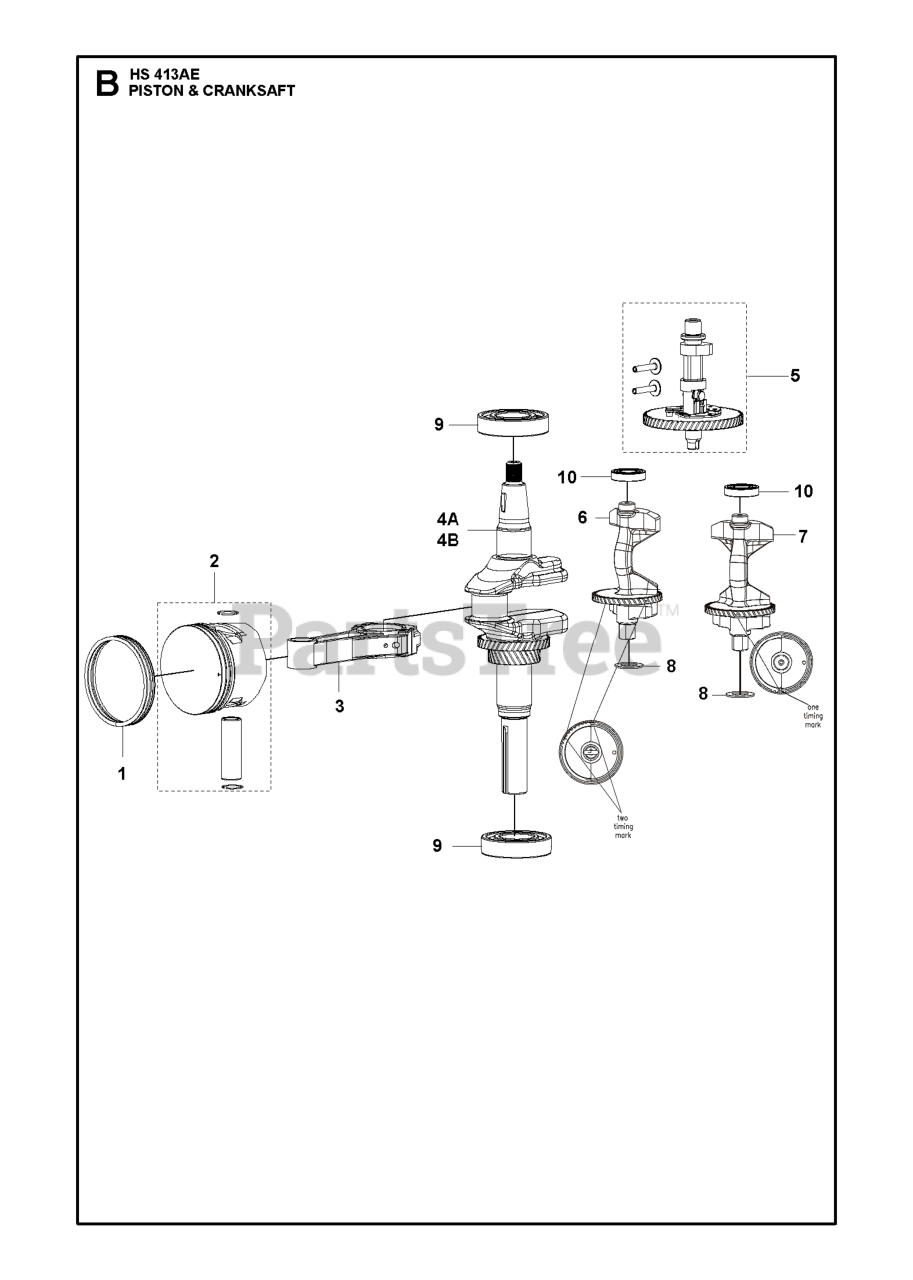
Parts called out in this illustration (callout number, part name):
3	CONNECTING ROD
6	SHAFT BALANCING SHAFT
7	SHAFT BALANCING SHAFT.
9	BALL BEARING BALL BEARING
10	BALL BEARING BALL BEARING
